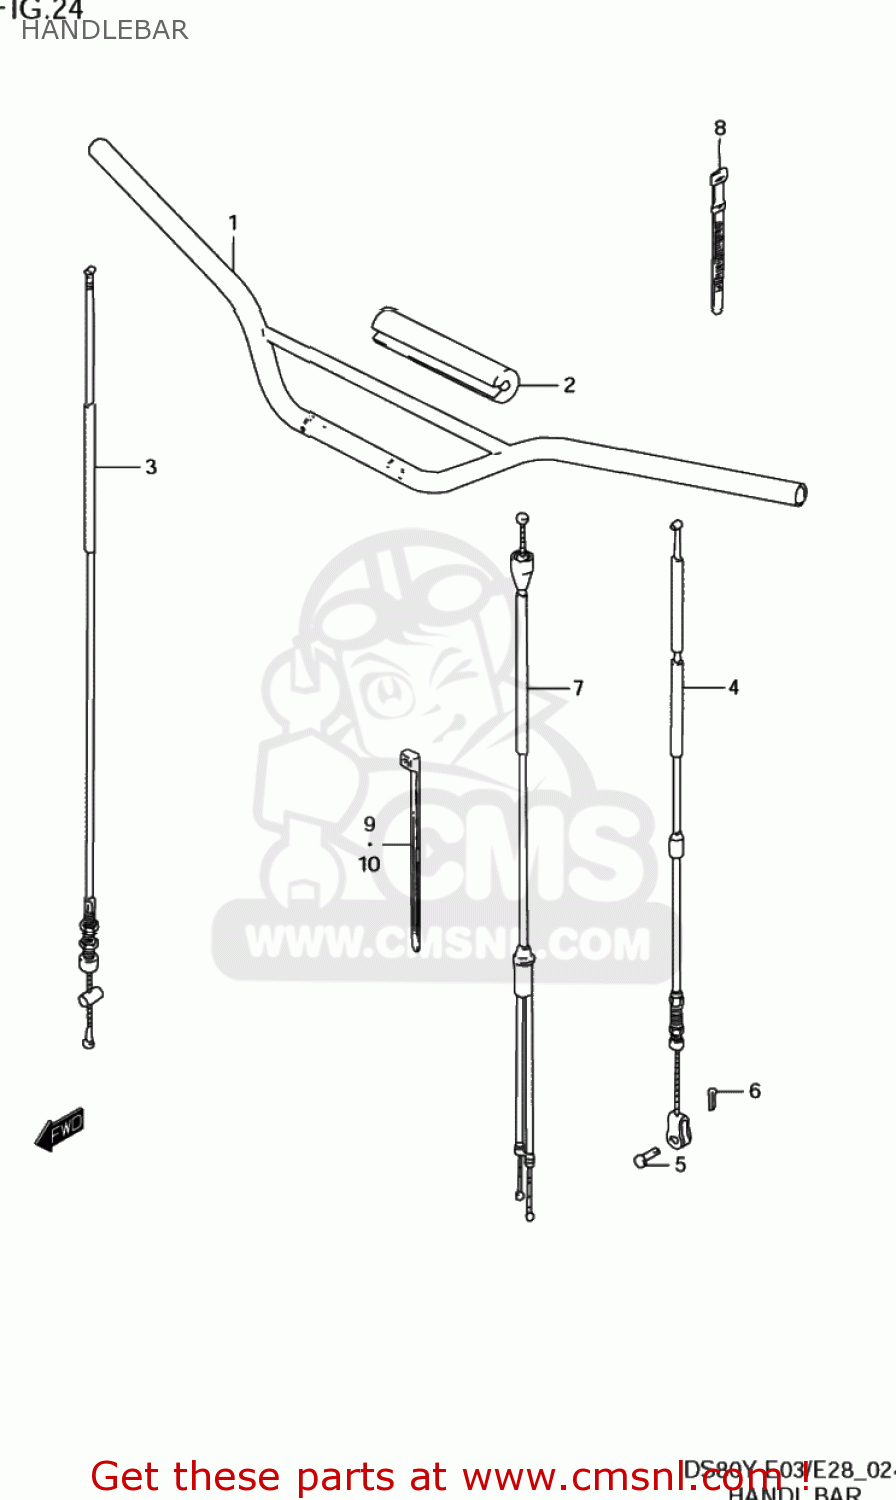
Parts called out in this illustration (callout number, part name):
1	HANDLEBAR
2	PAD,CROSSBAR
3	CABLE,FR BRAKE
4	CABLE ASSY,CLUTCH
5	PIN(L:13)
6	PIN
7	CABLE ASSEMBLY,THROTTLE
8	CLAMP(L:145)
9	CLAMP(L:125)
10	CLAMP(L:165)
